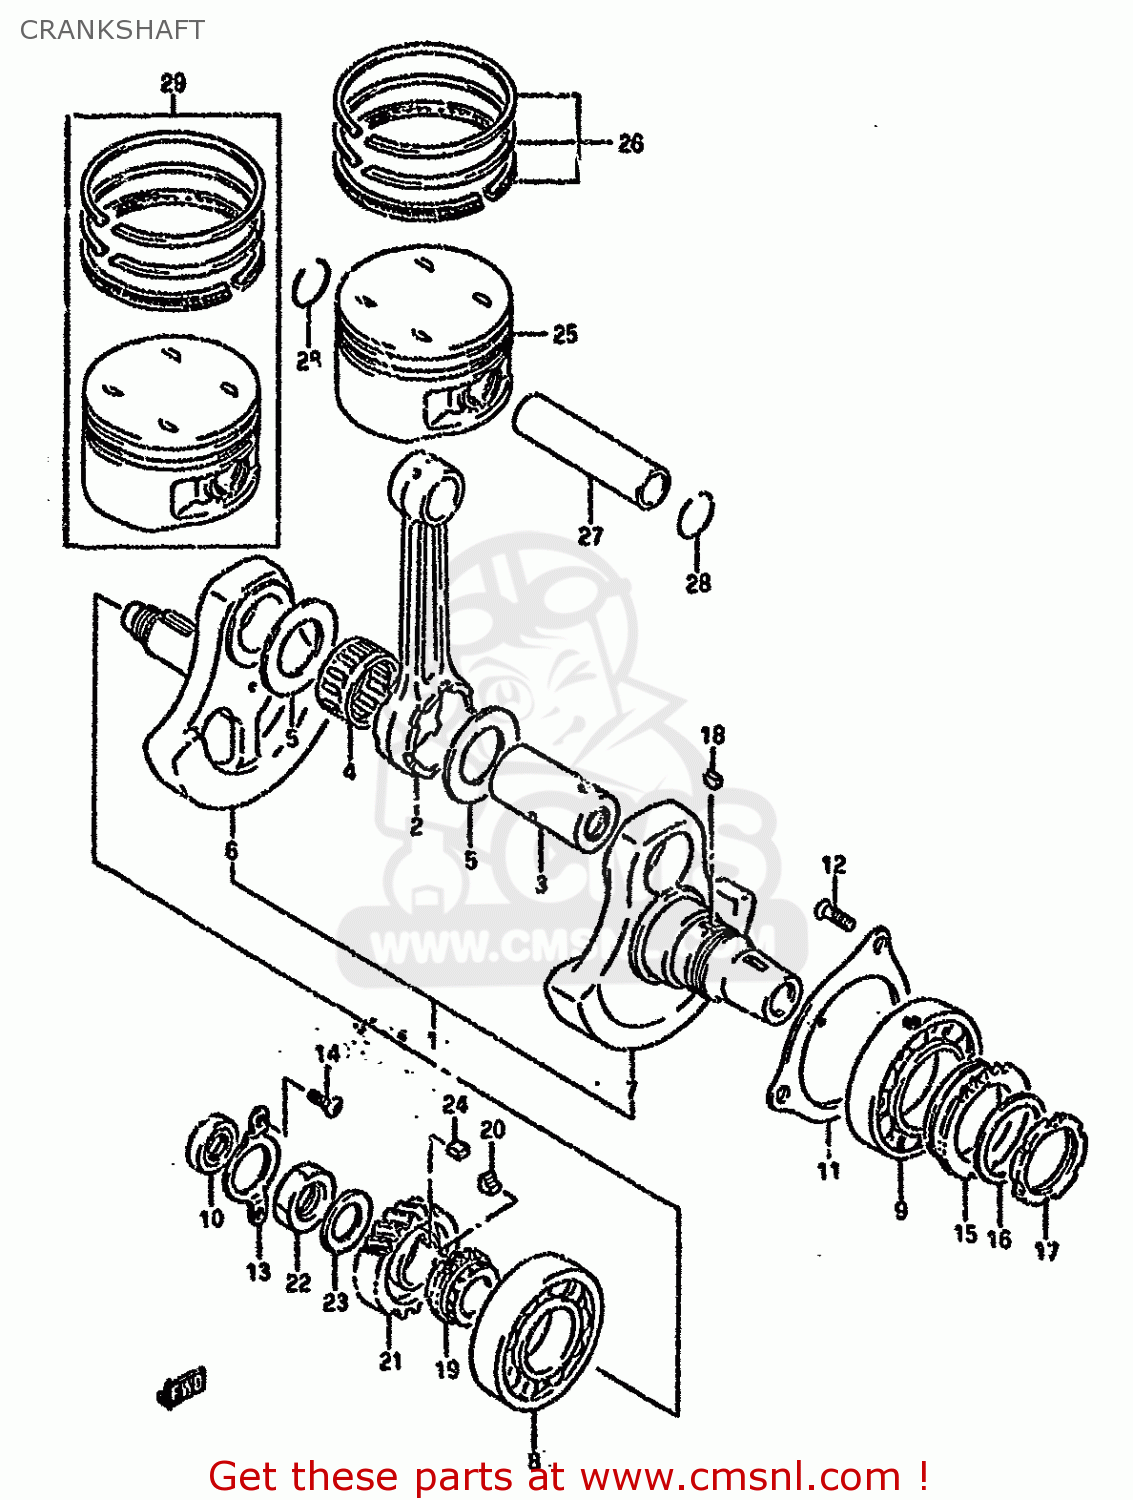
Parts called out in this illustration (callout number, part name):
1	CRANKSHAFT ASSEMBLY
2	ROD,CONNECTING
3	PIN,CRANK
4	BEARING
5	WASHER(35X55X1)
6	CRANKSHAFT,R
7	CRANKSHAFT,L
8	BEARING(35X80X21)
9	BEARING
10	SEAL,OIL(16X30X6)
11	RETAINER,CRANKSHAFT BEARING,L
12	SCREW
13	RETAINER,CRANKSHAFT BEARING,R
14	SCREW
15	SPROCKET,BALANCER DRIVE
16	WASHER
17	NUT,BAL DRIVE SPRKT
18	KEY
19	SPROCKET,CAM CHAIN DRIVE
20	KEY,SPROCKET
21	GEAR,PRIMARY DRIVE
22	NUT (20MM)
23	WASHER
24	KEY
25	PISTON
26	RING SET,PISTON
27	PIN,PISTON
28	CIRCLIP
29	PISTON SET(OS:0.5)
